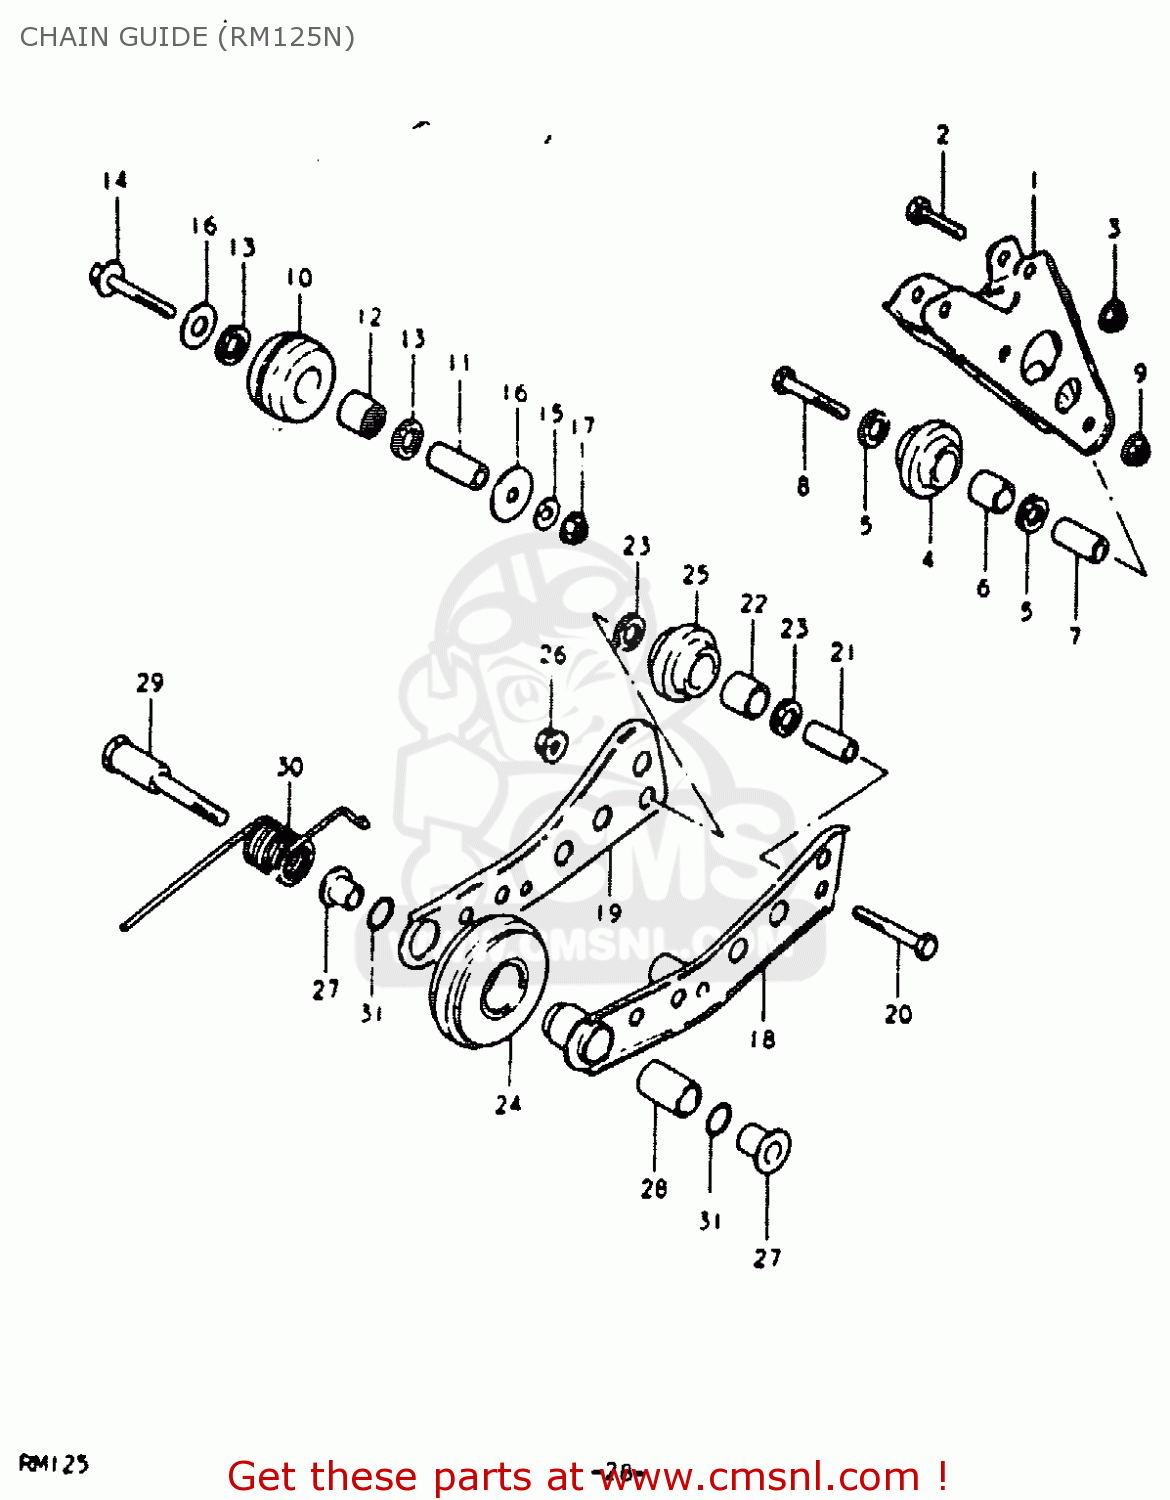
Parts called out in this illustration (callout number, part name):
1	GUIDE,DRIVE CHAIN
2	BOLT
3	NUT 6MM
4	ROLLER,CHAIN TENSIONER LWR
5	SEAL,OIL(10X14.4X3.5)
6	SPACER,CHAIN GUIDE
7	SPACER(6.2X10X22.5)
8	BOLT 6X35
9	NUT
10	ROLLER,CHAIN GUIDE
11	SPACER(6.2X10X22.5)
12	BEARING(10X14X15)
13	SEAL,OIL(10X14.4X3.5)
14	BOLT
15	WASHER
16	WASHER(6.5X18X1)
17	NUT 6MM
18	TENSIONER,CHAIN
19	PLATE,CHAIN TENSIONER
20	BOLT 6X35
21	SPACER(6.2X10X22.5)
22	SPACER,CHAIN GUIDE
23	SEAL,OIL(10X14.4X3.5)
24	ROLLER,CHAIN GUIDE
25	ROLLER,CHAIN TENSIONER LWR
26	NUT
27	SPACER,CHAIN TENSIONER
28	BUSHING,CHAIN TENSIONER
29	BOLT
30	SPRING
31	O RING(D:1.3,ID:9.6)
